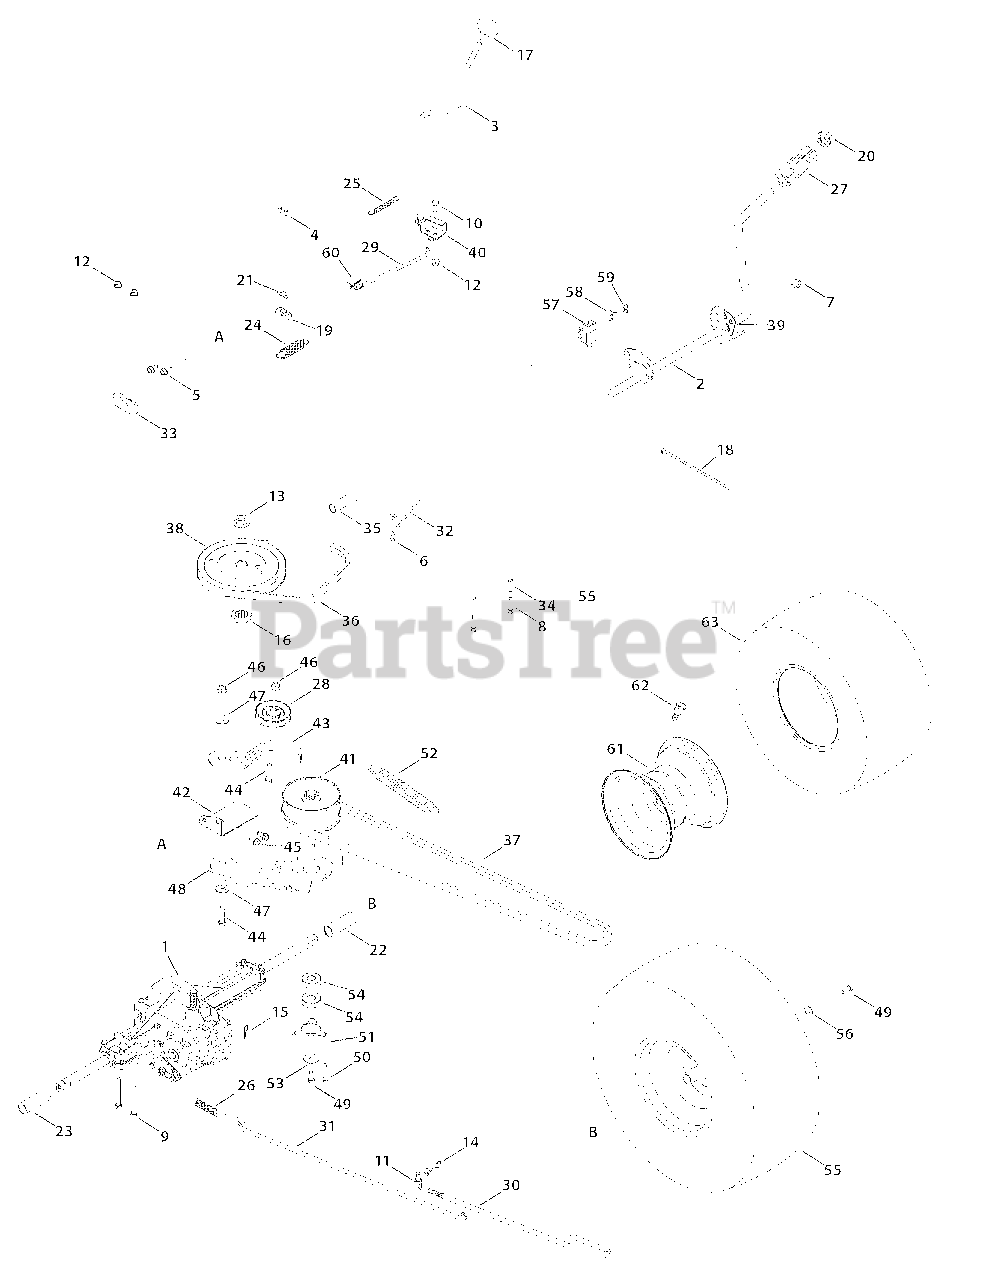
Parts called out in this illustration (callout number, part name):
1	Transmission Drive Assembly
2	Pedal Assembly - Powder Black
2	Pedal Assembly - Red
2	Pedal Assembly - Black Jack
3	Shaft Lever Assembly
4	Screw, 8-18:0.500
5	Screw, 5/16-18 x .750
6	Screw, 1/4-20 x 0.500
7	Screw, 5/16-18 x 0.625
8	Screw, 1/4-20 x 1.250
9	Hex Screw, 5/16-18 x .625
9	Hex Screw, 5/16-18 x 2.75
10	Hex Screw, 5/16-18 x .75
11	Ferrule, 3/8-24 X .375 DIA.
12	Flangelock Nut, 5/16-18
13	Flange Nut, 9/16-18
14	Cotter Pin INT- .125 DIA
15	Bow-Tie Cotter Pin, 72
16	Pulley Hub, 5/8 SPLINE
17	Shift Knob
18	Cable Tie
19	Short Spring Switch
20	Push Cap, 5/8
21	Plate Insulator Nut
22	Sleeve, .758 x .821 x 3.3125
23	Sleeve, .758 x .821 x 2.4375
24	Spring Extension, .80 OD x 3.28 LG
25	Spring Extension, .38 OD x 3.25 LG
26	Spring Extension, .59 OD x 4.00 LG
27	Foot Pad, 4.0 LONG
28	Idler Pulley
29	Shift Rod, 46"
29	Shift Rod, 38/42"
30	Variable Speed Control Rod
31	Brake Rod
32	Belt Keeper Rod
33	Spacer, T-Axle, 46" Only
34	Spacer, .260 x .375 x 1.030 LG
35	Spacer, .640 ID x .76 OD x 2.63
36	V Belt, 5L 35.25 POLY
37	V Belt, 5L 70.90 POLY
38	V Pulley 7.25 DIA SPUN
39	Pedal Support Bracket
40	Shaft Adjust Bracket
41	Variable Speed Pulley Assembly
42	Transmission Bracket Assembly
43	Idler Bracket Assembly
44	Hex Screw, 3/8-16 x 1.75
45	Screw, 5/16-18 x 0.750
46	Flangelock Nut, 3/8-16
47	Shoulder Spacer, .625 ID x .169
48	Bracket Assembly
49	Hex Screw, 5/16-24 x .750
50	Screw, 1/4-20 x 1.500
51	Bearing Cup
52	Extension Spring, .94 OD x 6.74 LG
53	Flat Washer, .330 x 1.25 x .06:HT
54	Ball Bearing, 17 x 40 x 12
55	Wheel, 20 x 8 x 8, 46"
55	Wheel, 20 x 8 x 8, 38/42" Grey
55	Wheel, 20 x 8 x 8, 38/42" Yellow
56	Bell Washer, .340 x .872 x .060
57	Switch Interlock
58	Plate Switch
59	Shoulder Screw, #10-32 x .500
60	Shift Plate Bearing
62	Valve
63	Tire, 20 x 8 x 8
